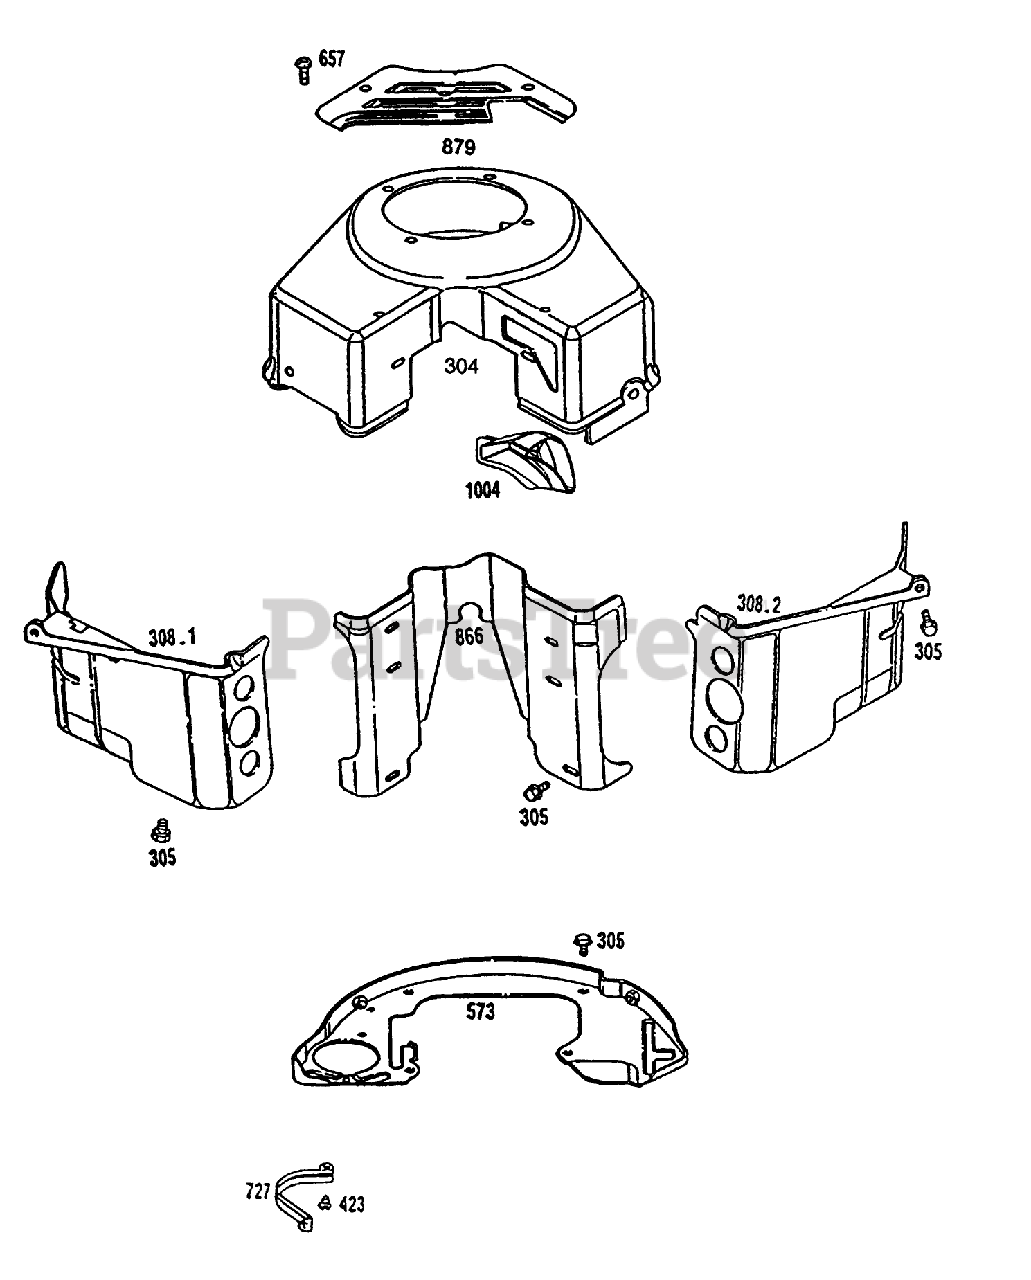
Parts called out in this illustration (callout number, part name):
304	HOUSING - BLOWER
305	BRIGGS 805406
423	BRIGGS-805260
573	BRIGGS 807663
657	BRIGGS 805009
727	BRIGGS-805505
866	Valley Cover-Air Guide
